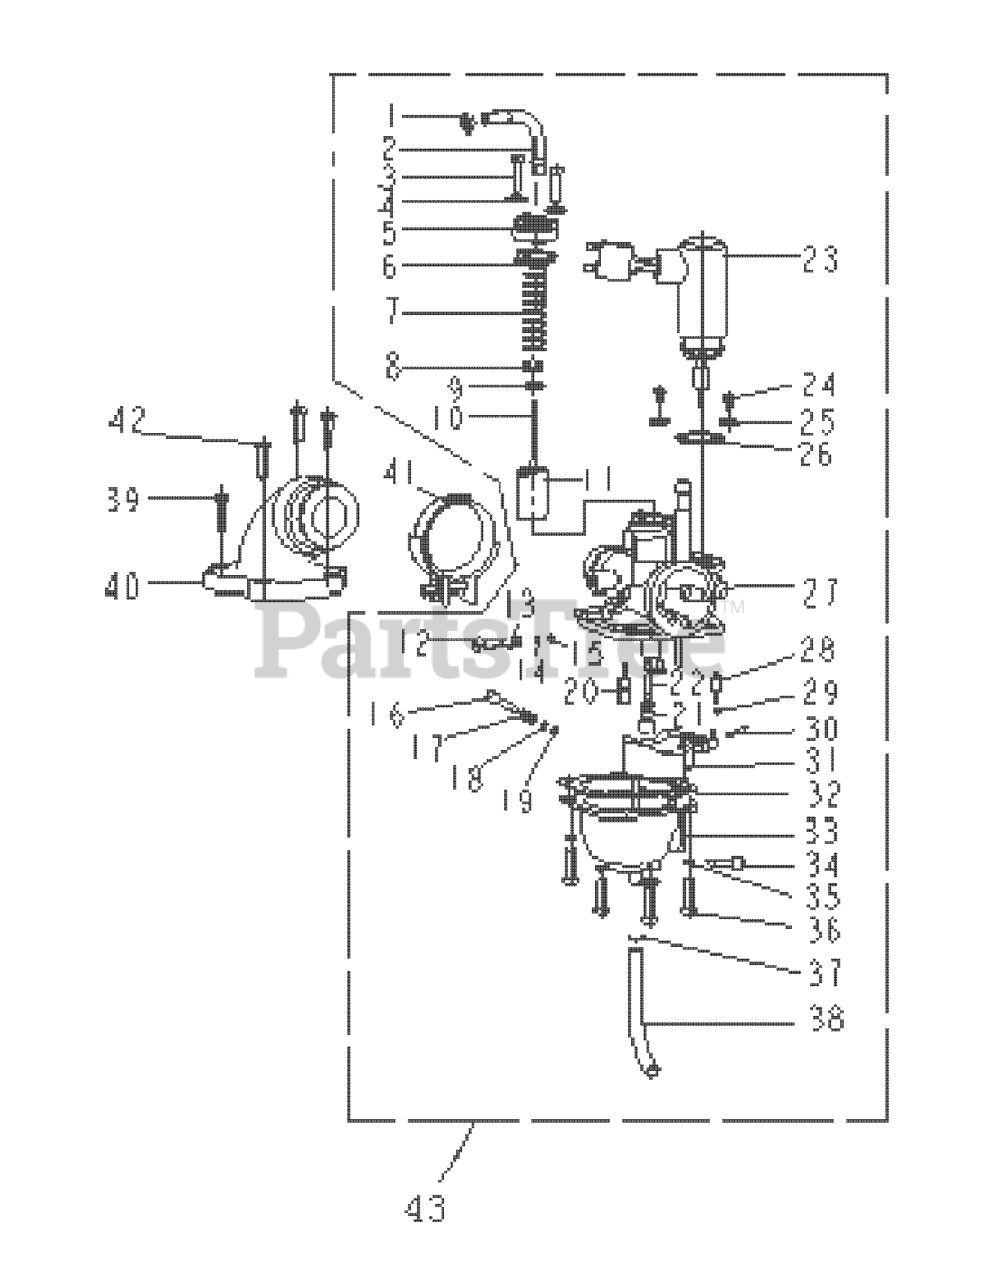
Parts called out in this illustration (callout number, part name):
1	FIX SCREW
2	INSTRAINT PIPE
7	SPRING, RETURN
8	CLIP, V-SHAPE
10	NEEDLE, JET
11	VALVE, PISTON
12	SCREW, IDLE SPEED
13	SPRING, SPEED SCREW
14	WASHER, SPEED SCREW
15	O -RING, SPEED SCREW
16	SCREW, AIR
17	SPRING, AIR SCREW
18	WASHER, AIR SCREW
19	O-RING, AIR SCREW
20	JET, IDLE
21	JET, MAIN
22	JET, NEEDLE
23	THERMO ASSY
27	BODY, CARBURETOR
28	VALVE, NEEDLE
30	PIN, FLOAT
33	CHAMBER, FLOAT
38	HOSE, DRAIN
40	PIPE, INTAKE
43	CARBURETOR ASSY
